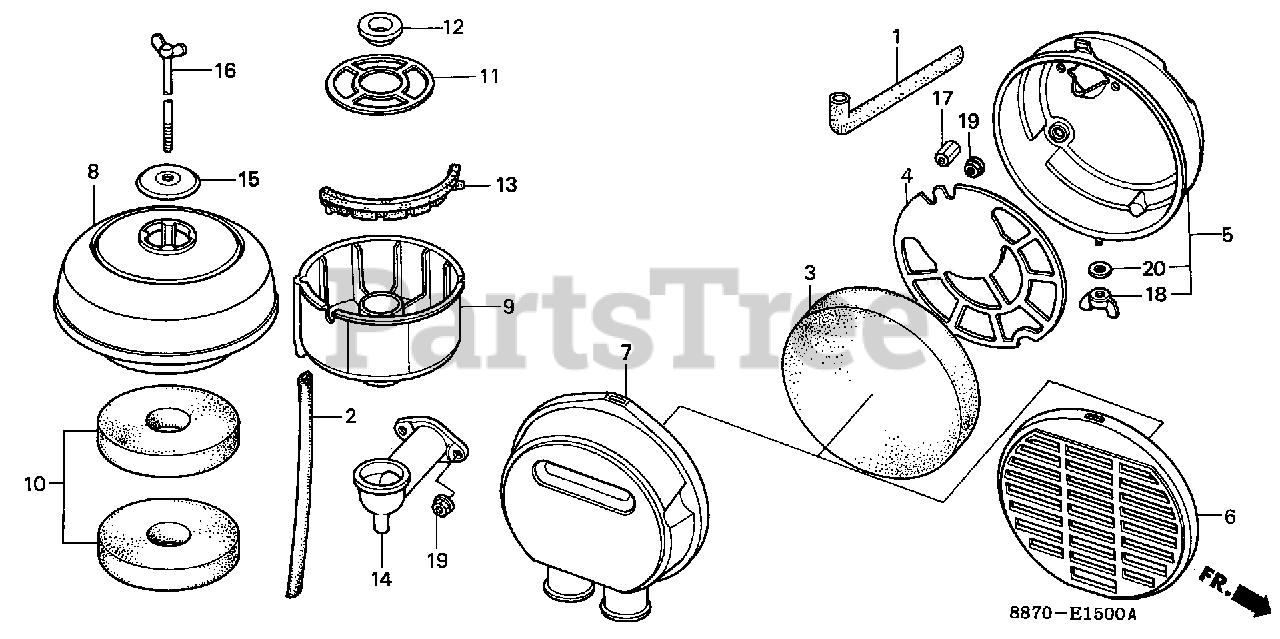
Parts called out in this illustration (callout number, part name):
2	TUBE, BREATHER
8	BODY, CLEANER
9	PAN, AIR CLEANER OIL
10	ELEMENT, AIR CLEANER
11	GRID, AIR CLEANER
12	COLLAR, AIR CLEANER (NOT AVAILABLE)
14	ELBOW, AIR CLEANER
15	CAP, AIR CLEANER
16	BOLT, AIR CLEANER
19	NUT, FLANGE (6MM)
